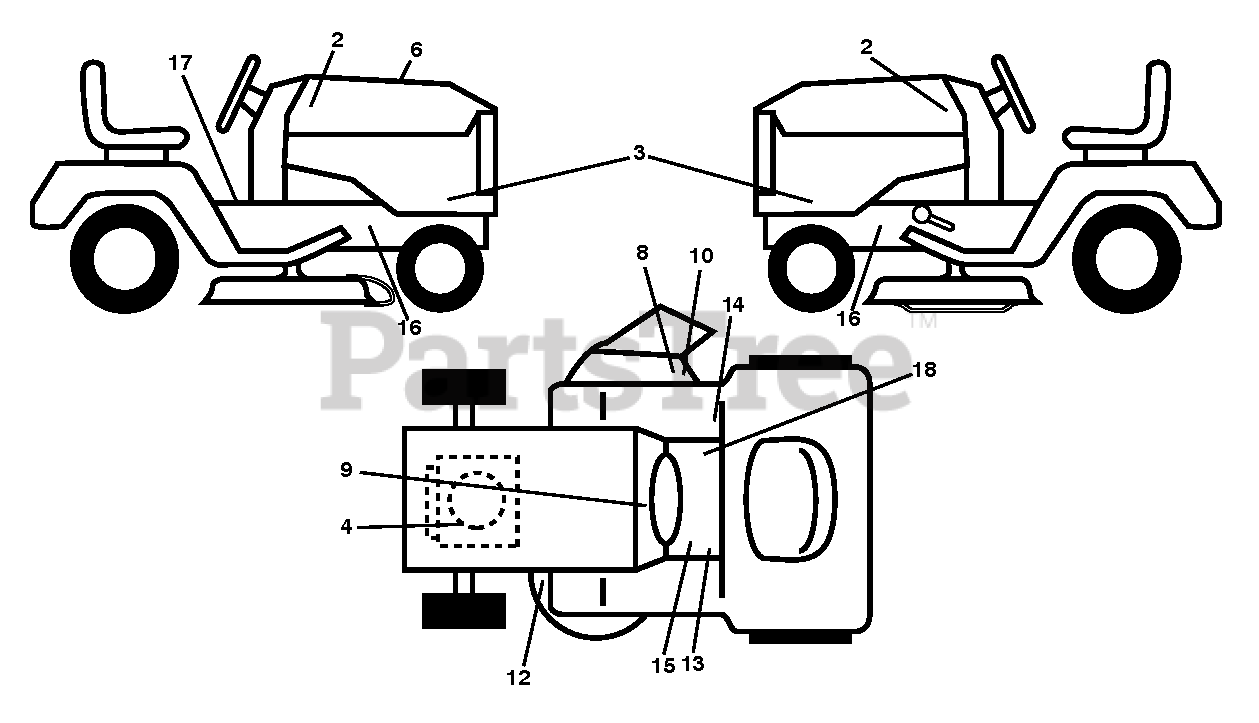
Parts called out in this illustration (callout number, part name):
2	DECAL.BADGE.170MM.TEXTLOGO.
3	DECAL.SDPNL.HUSGT2.668.SET
4	DECAL
6	DECAL.RPL.KW.FS651.TLW.46R.K46
8	DECAL.INTERNATIONL.CUTFINGER
9	DECAL BTRY SYMBOLS
10	DECAL, DEFLECT WARNING
12	DECAL V BELT SCHEMATIC
13	LABEL
14	Decal, Fender 100 DB/CE
15	DECAL
17	DECAL PARK BRAKE
18	DECAL
